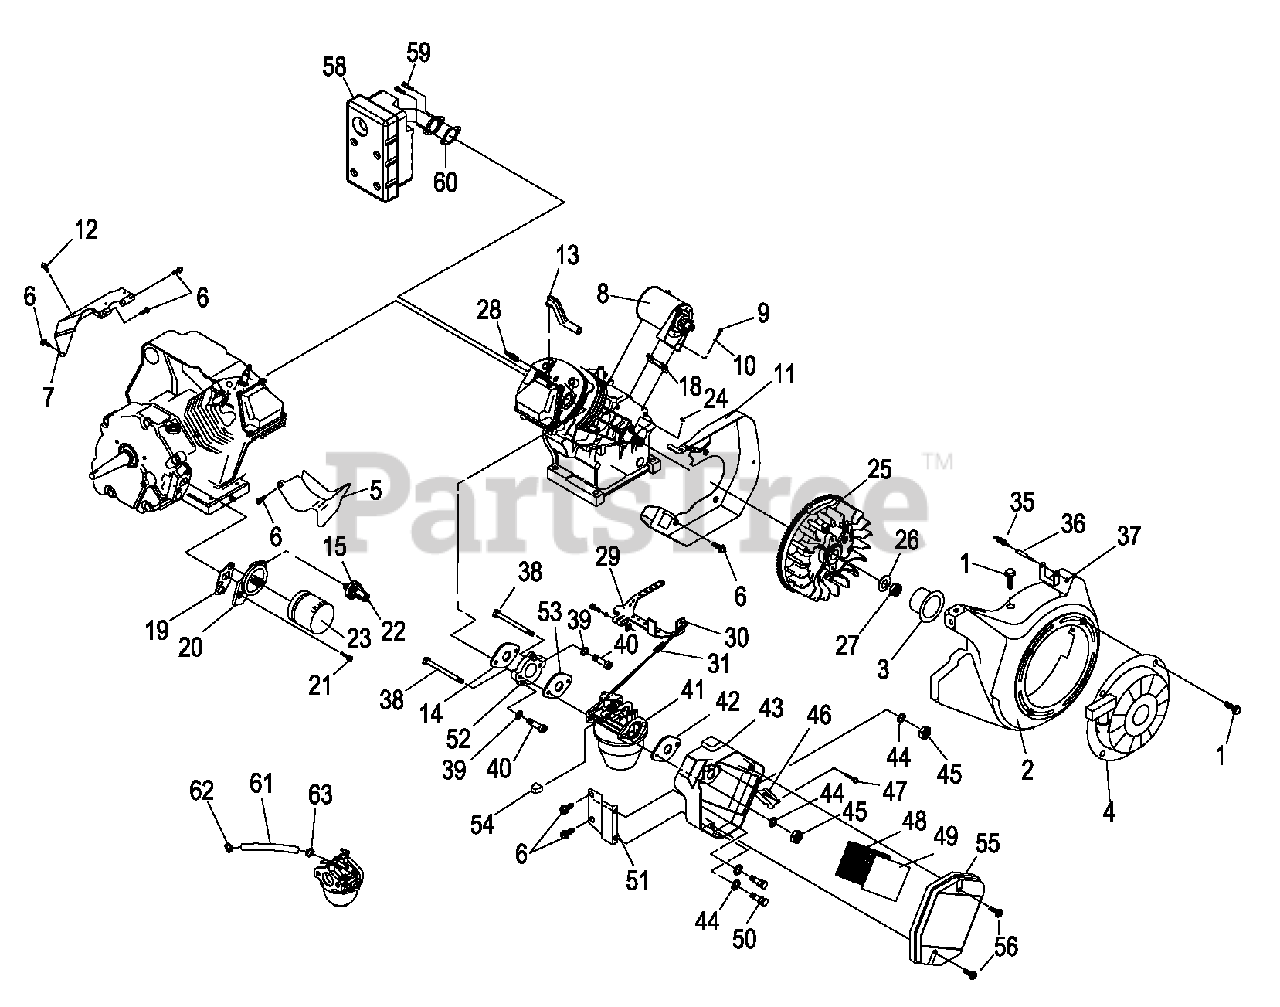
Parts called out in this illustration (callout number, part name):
1	SCREW HHTT M6-1.0 X 8 ZYC
2	ASSEMBLY, BLOWER HOUSING
3	PULLEY STARTER LARGE FRAME
4	RECOIL STARTER LARGE FRAME
5	WRAPPER, BOTTOM 12 HP HS
6	SCREW HHTT M6-1.0 X 10 YELLOW CHROME
7	WRAPPER, TOP REGULAR STEEL
8	ASSEMBLY, STARTER 46
9	SCREW, SHC M8-1.25 X 45 G12.9
10	WASHER, LOCK M8-5/16
11	BACKPLATE, W/ ELECTRIC START
12	SCREW, HHTT M8-1.25 X 16 YELLOW CHROME
13	HOSE, BREATHER GH410 ENGINES
14	GASKET, INTAKE ADAPTER
15	SCREW PPHM #8-32 X 1/4
18	SPACER, ENDFRAME GH 410
19	GASKET,OIL FILTER ADAPTER
20	ADAPTER, OIL FILTER NO TAPPED HOLES
21	SCREW, SHC M8-1.25 X 30 G12.9
22	SWITCH, HOBBS OIL PRESSURE 5PSI
23	FILTER, OIL BLACK 75 LONG
24	KEY, WOODRFF 4 X 19D
25	FLYWHEEL, WITH RING GEAR 27 DEGREE
26	WASHER,BELV-20 X 2.2
27	NUT HEX M20-1.5 G8 YLW CHROME- FLYWHEEL
28	SPARKPLUG, CHAMPION RC14YC
29	ASSEMBLY,GOVERNOR LEVER 12HP
30	ROD, GOVERNOR CONTROL
31	SPRING, ANTI-LASH
32	ENGINE HARNESS, PORTABLE
35	SPRING GOVERNOR 320/360/410
36	BOLT, GOVERNOR ADJUSTMENT M5
37	NUT, HEX LOCK M5-0.8 NYLON INSERT ZINC
38	BOLT, CARBURETOR MOUNTING
40	SCREW, SHC M6-1.0 X 20 G12.9 ZINC PLATED
41	CARBURETOR, 410HS
42	GASKET, AIR CLEANER
43	BASE, AIR CLEANER 410 HI FLOW
44	WASHER, FLAT M6
45	NUT, HEX LOCK M6-1.0 NYLON INSERT
46	PLATE, SPITBACK
47	SCREW, PLASTITE #8 X .37 LONG
48	ELEMENT, AIR FILTER
50	SCREW, HHC M6-1.0 X 16 W/ LOCK WASHER
51	BRACKET, AIR CLEANER
52	ADAPTER, "K"
53	GASKET, CARBURETOR/MANIFOLD
54	KNOB, CHOKE LEVER
55	COVER, AIR CLEANER 13GN
56	BOLT, AIR CLEANER COVER
58	MUFFLER, 410 SIDE-OUT ALUMINIZED
59	SCREW, SHC M8-1.25 X 20 G12.9
60	GASKET, EXHAUST
61	HOSE,1/4" SAE30R7 SETIFLEX 6"
62	CLAMP, HOSE BAND 1/2"
63	CLAMP, HOSE WORM GEAR
64	GOLF TEE, FUEL LINE PLUG
